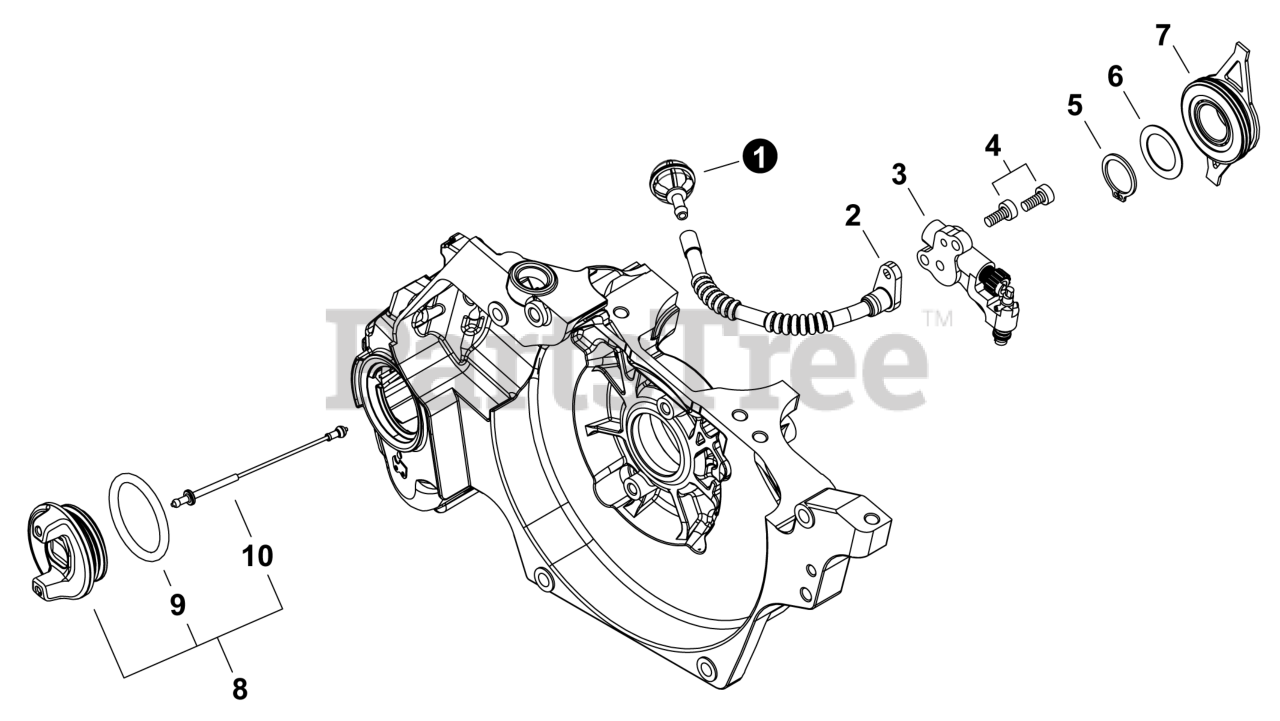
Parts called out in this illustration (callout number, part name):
1	FILTER, OIL
2	PIPE, OIL
3	AUTO-OILER ASSY
4	BOLT, TORX 4x12
5	RING, RETAINING 15
6	WASHER 15.5x22.5x0.5
7	GEAR, WORM
8	CAP ASSY, OIL
9	O-RING 29
10	CONNECTOR, CAP
